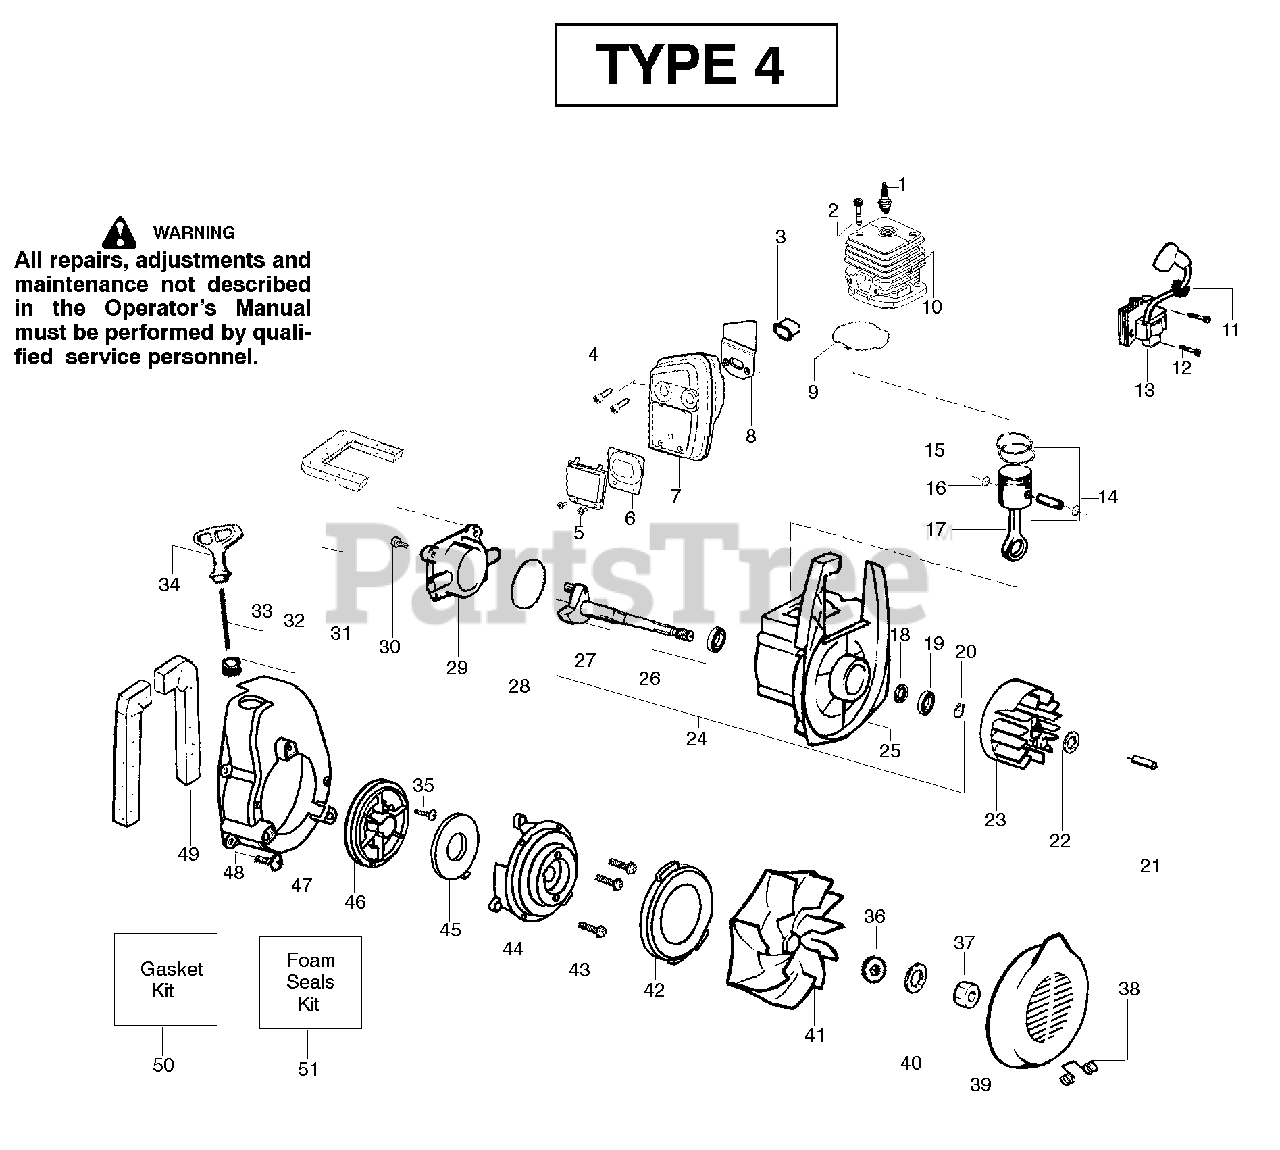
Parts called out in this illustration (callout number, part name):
1	Spark Plug (RCJ-6Y)
3	Insulator-Heat
4	Screw-Muffler-Internal
5	Screw
6	Kit-Spark Screen
7	Kit-Muffler
8	Gasket-Baffle (kit)
9	Gasket-Cylinder (kit)
11	Grommet-Ign. Module
12	Screw-Ignition Module
13	Ignition Module
14	Kit-Piston
15	Piston Ring
16	Retainer-Piston Pin
17	Assy-Connecting Rod
18	Seal-Crankcase
19	Bearing-Outer
20	Retainer Ring-C'shaft
21	Spacer-Flywheel
23	Assy-Flywheel
24	Assy-Crankcase/Crank shaft
25	Assy-Crankcase
26	Bearing-Inner
27	Assy-Crankshaft
28	O-ring-C/case (kit)
29	Cover-Crankcase
30	Screw
31	Foam-219mm (kit)
32	Eyelet-Flange
33	Kit-Rope
34	Handle-Starter
36	Washer-Belleville
38	Spring-Return Cover
41	Assy-Impeller
44	Housing-Pulley
45	Spring-Starter
46	Kit-Starter Pulley
48	Screw
49	Foam-182mm (kit)
50	Kit-Gasket
51	Kit-Foam Seals
